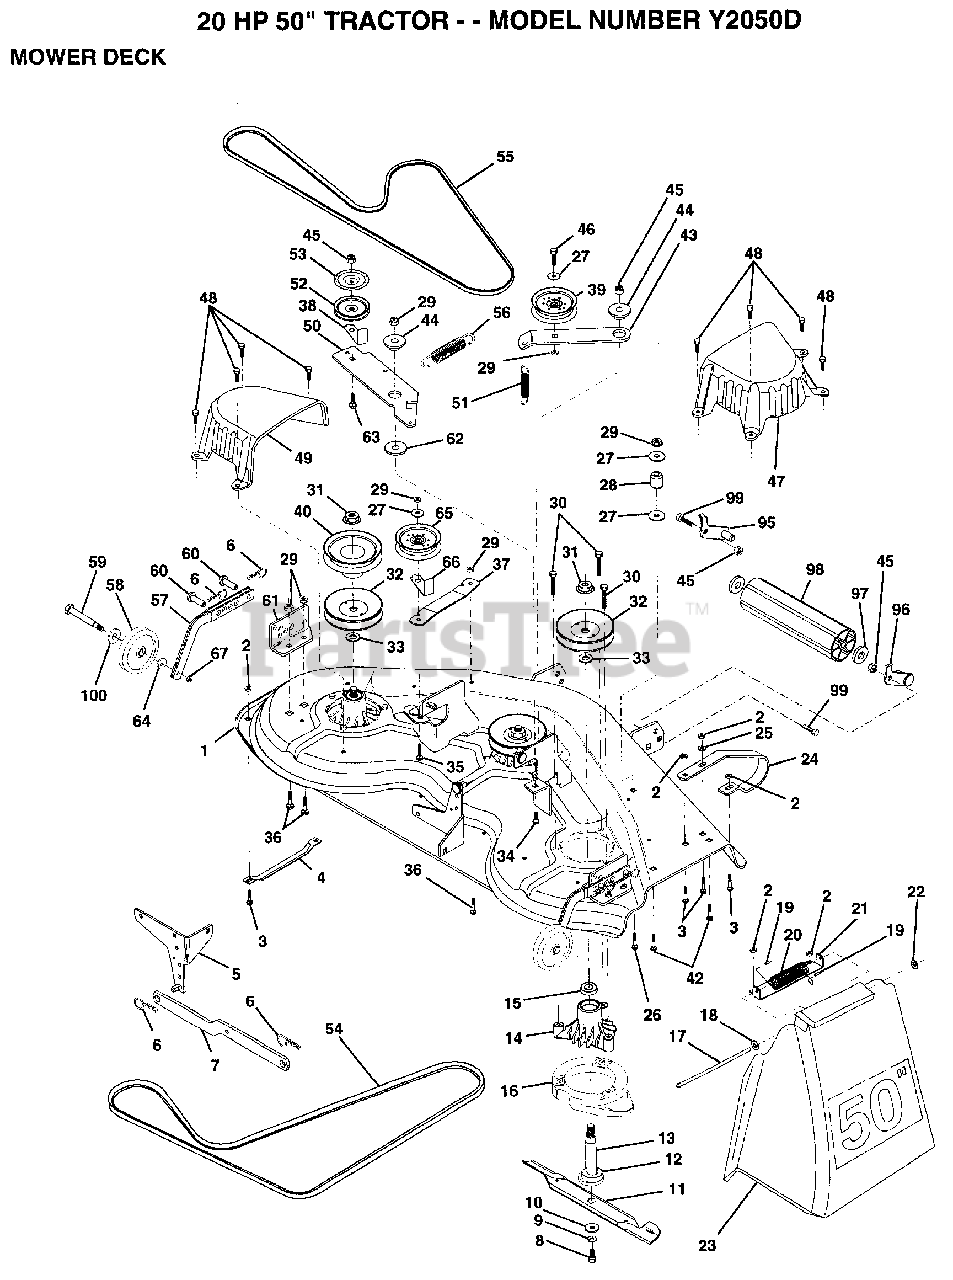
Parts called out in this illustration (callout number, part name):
1	DECK ASM MWR 50VT
2	NUT
4	RUNNER-LH M
5	BRKT.ASM.SW.44/50
8	BLADE BOLT
10	WASHER.HARD.BLADE
11	"BLADE.50"" HD"
12	BEARING.BALL
13	SHAFT.ASM.W/BRNG
14	HOUSING.MAND.44.V
15	BEARING
17	ROD-HINGE T
18	WASHER
19	CAP-SLEEVE LT
20	SPRING TORSION
21	BRKT DEFLECTOR
22	NUT PUSH M
23	DEFLECTOR
24	"RUNNER RH 50"" DK"
25	WASHER M
26	BOLT
27	WASHER
29	NUT
33	WASHER
34	BOLT.3/8-14X1.25
35	BOLT
36	BOLT D
37	STIFFENER.ARM.IDL
39	FLAT IDLER PULLEY
40	"PULLEY.DRIVEN.44"""
42	BOLT
43	"ARM.IDLER.SEC.44"""
44	SPACER RETAINER
47	"COVER.MAND.RH.44"""
48	SCREW.1/4-20X5/8
49	COVER.MANDREL.LH
50	ARM.IDLER.PRIMARY
51	"SPRING.SEC.44""VEN"
52	PULLEY.IDLER.VGRO
53	SHIELD.IDLER.44.V
54	BELT V PRIM 50
55	BELT.V.GDRIVE.95
56	SPRING.EXT.DECK.
57	BAR.ASM.GUAGE.WHL
58	WHEEL.GAGE.BLK.PL
59	BOLT M
60	PIN.CLEVIS
61	BRACKET.GUAGE.WHL
62	HARDENED WASHER
63	BOLT.3/8-16X1.50
64	WASHER
65	IDLER-FLAT T
67	LOCKNUT
68	BOLT
71	WASHER
72	WASHER
